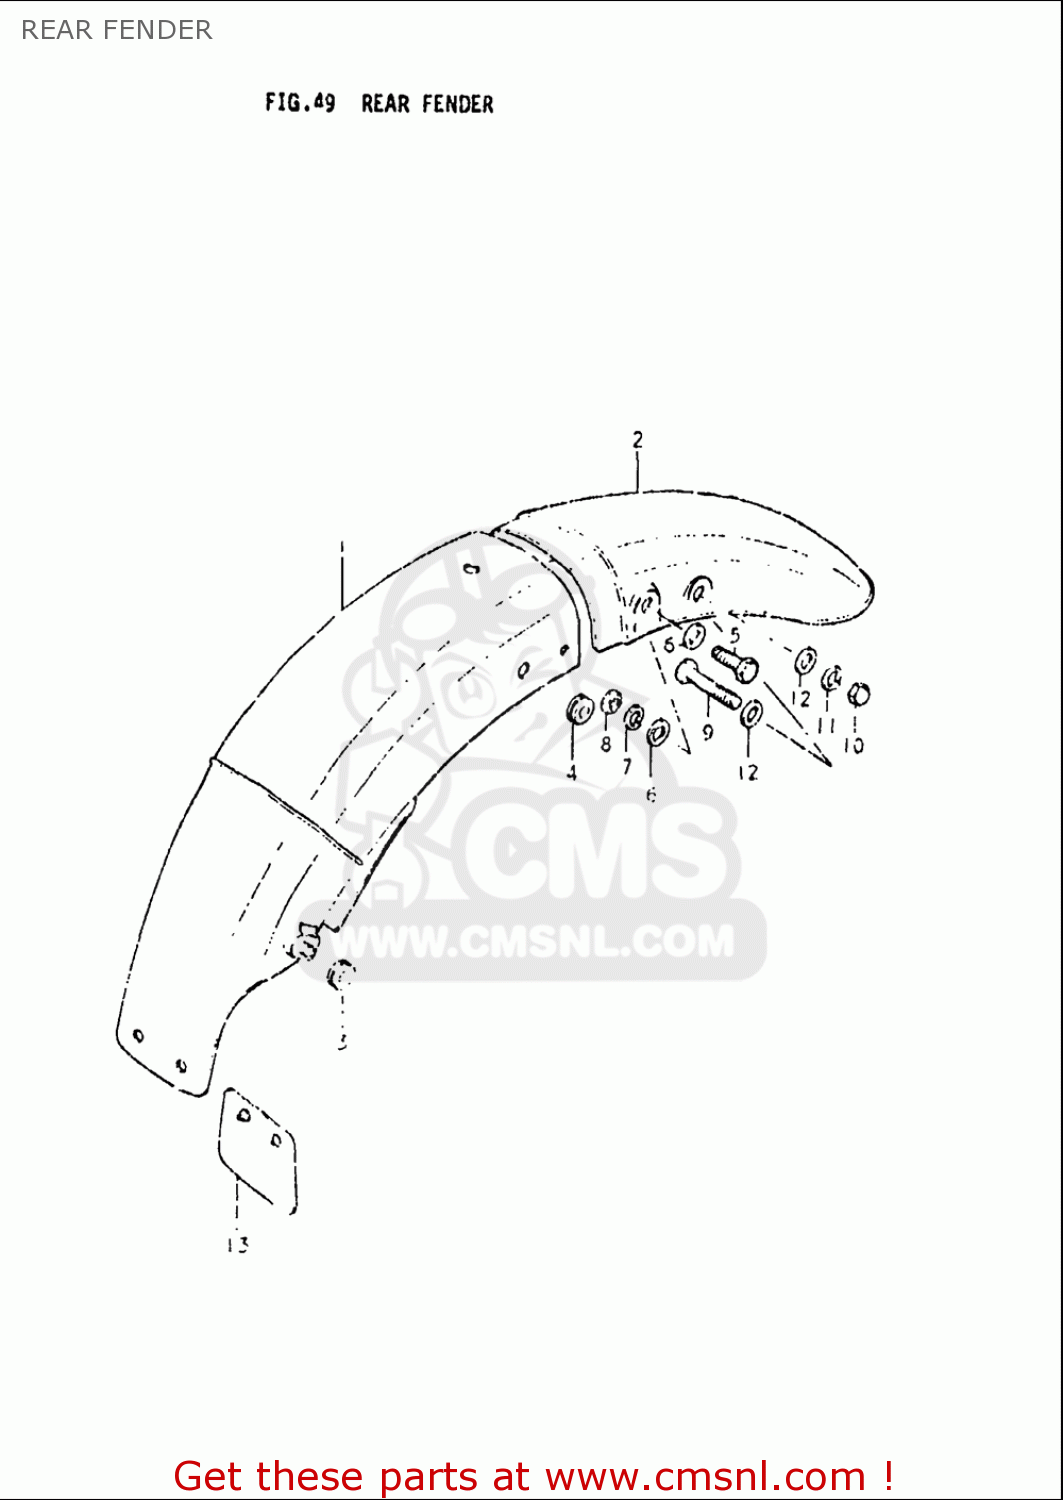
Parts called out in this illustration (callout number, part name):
3	CUSHION
4	CUSHION
5	BOLT
6	WASHER
7	WASHER,LOCK
8	NUT
9	BOLT
10	NUT
11	WASHER,LOCK
12	WASHER
13	GUIDE,RR FENDER MUD
